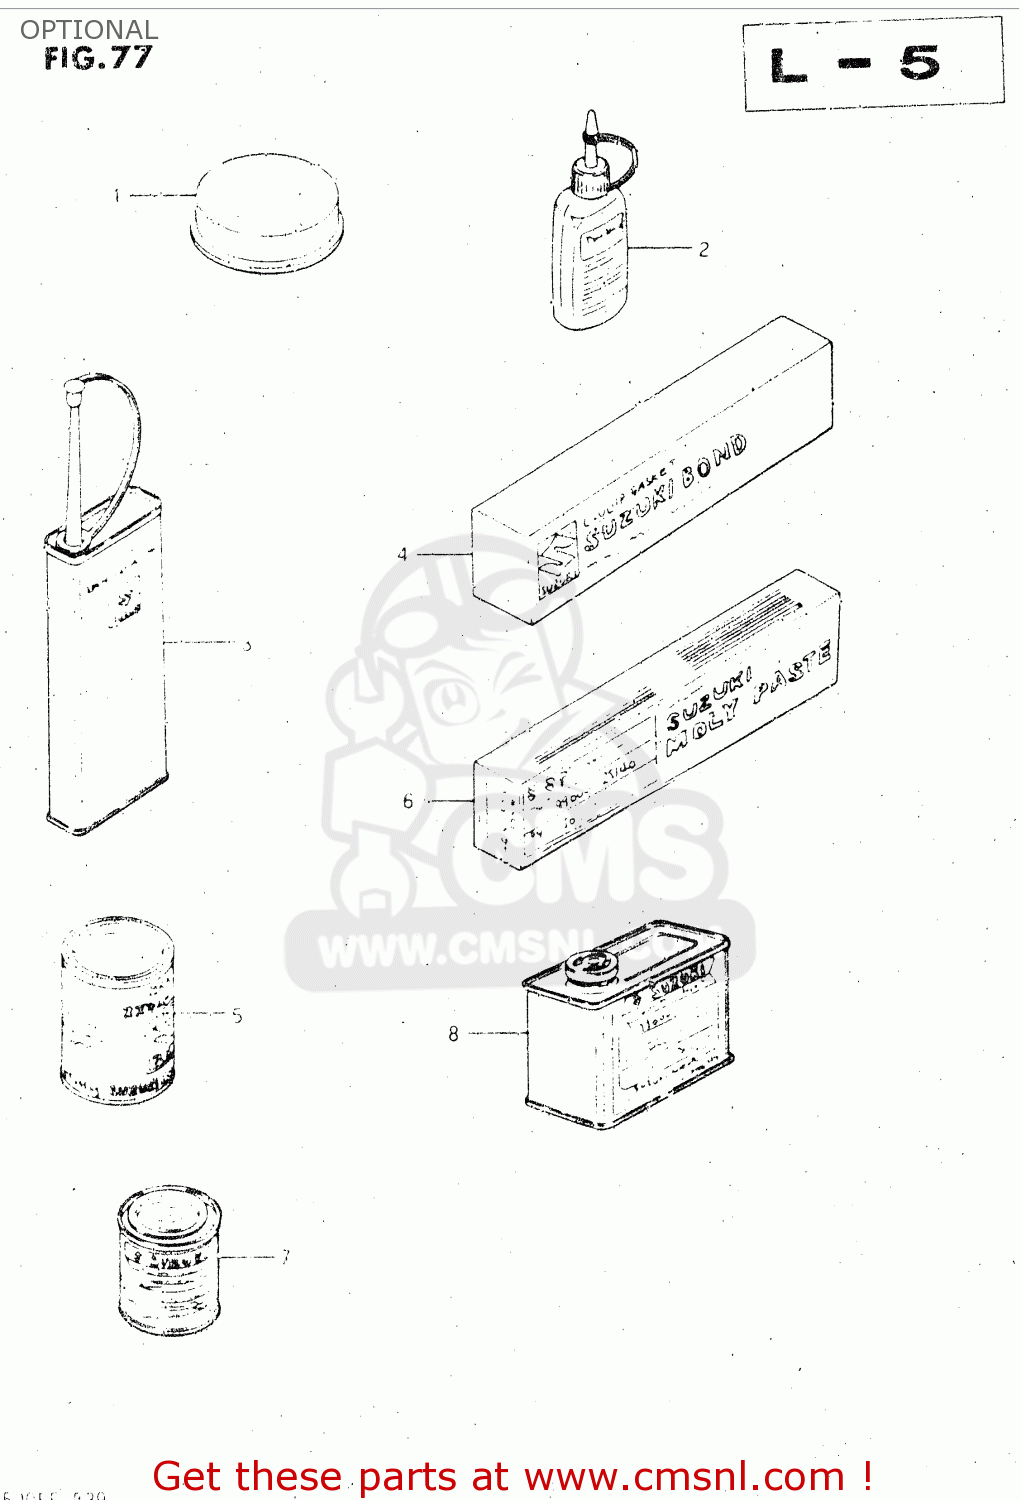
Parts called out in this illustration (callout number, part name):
1	GREASE,PBC FOR BRK PAD 20G
2	THREAD LOCK NO.1342
3	THREAD LOCK NO.1401 CLEAR 200G
4	LIQUID GSKT NO.1207B 100G BLK
5	GREASE(C)EP2 LITHIUM 150G
6	SUZUKI MOLY PASTE
7	PAINT BLIGHT S
8	PAINT (SPACE BLACK)
